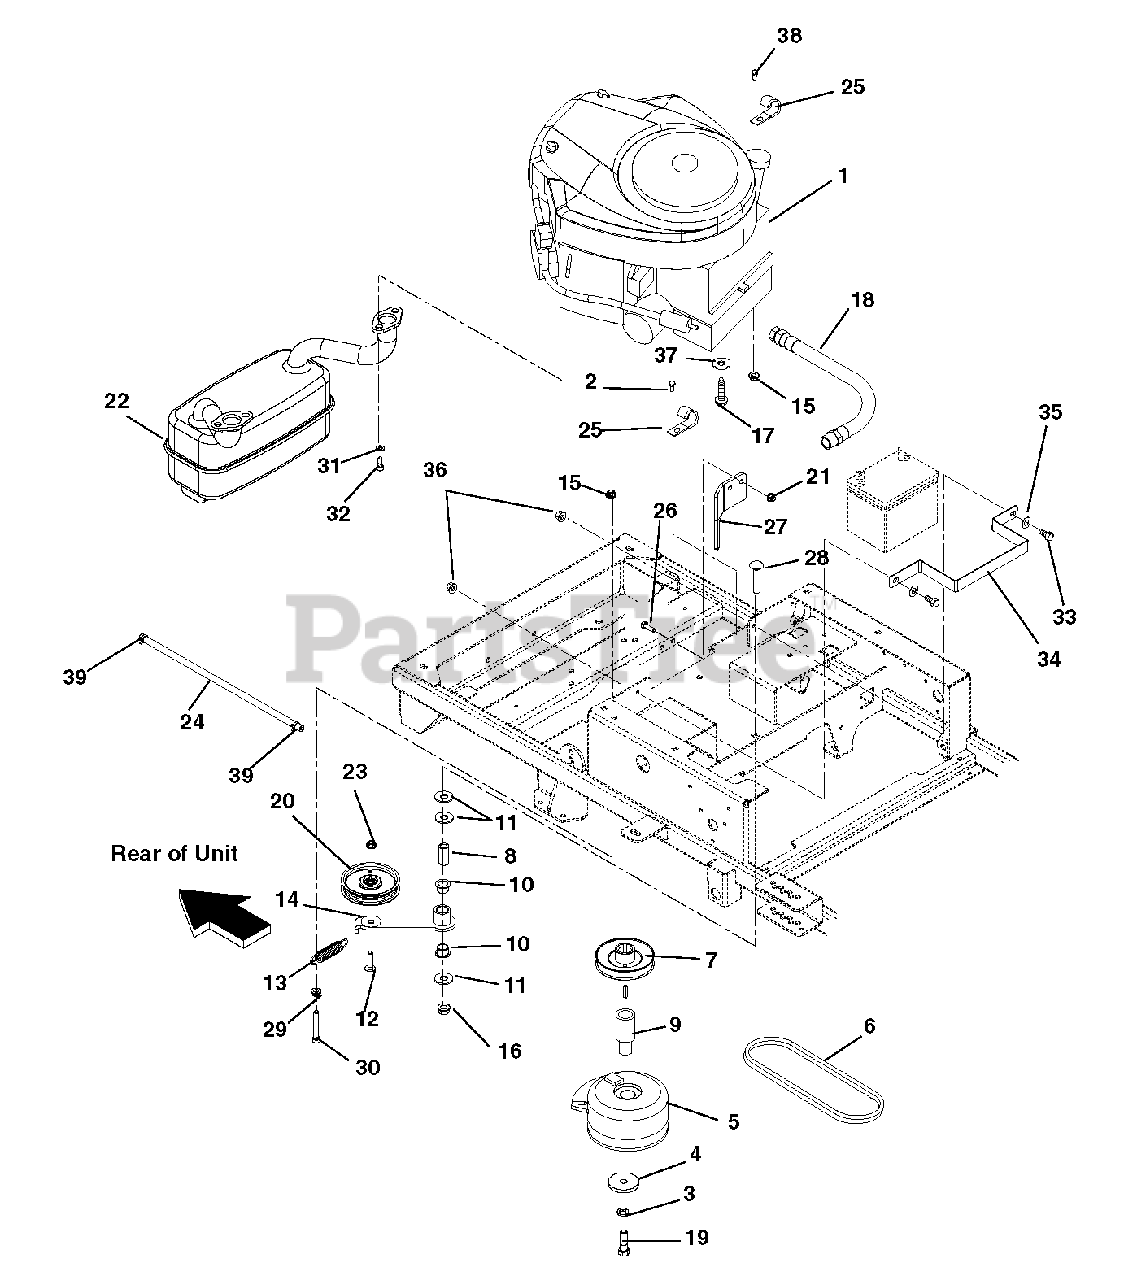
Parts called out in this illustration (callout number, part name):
1	Engine, FR651-22 Kawasaki Twin (915154)
2	Screw, Tapping .250-20 x .37 Hex Washer Head
3	Washer, Locking .44 x .109 Regular
4	Washer, Flat Steel .469 x 2.00 x .25
5	Clutch, ZTXL
6	Belt, HA 62.50 Wrapped
7	Pulley, V 4.5 x 1.5 AB Section with Key
8	Bushing, Sleave .500 x .750 x .1.560
9	External, Crankshaft Lower
10	Bushing, Flange 0.75 x 0.875 x .625 x 1.125
11	Washer, Flat Steel .563 x 1.38 x .109
12	Bolt, Round Head Square Neck .38-16 x 1.50 Grade 5
13	Spring, Tension .105 x .812 x 3.88
14	Weldment, Ground Drive Idler Arm
15	Nut, 3/8-16 Flange Nyloc
16	Nut, Locking Top Flange .50-13
17	Bolt, Hex .38-16 x 1.25
18	Hose Assembly, Oil Drain
19	Bolt, Hex .44-20 x 4.50 Grade 8
20	Assembly, 4" Idler
21	Nut, .31-18 Nyloc Flange
22	Muffler
23	Nut, Locking Top Flange .38-16
24	Assembly, Fuel Hose
26	Bolt, Hex .31-18 x 1.00 Grade 5
27	Clutch Stop
28	Bolt, Round Head Square Neck .50-13 x 2.50 Grade 5
29	Nut, Flange .375-16
30	Bolt, Hex .38-16 x 2.50 Grade 5
31	Washer, Locking .31 x .078 Regular
32	Screw, Cap .31-18 x .75
33	Bolt, Hex .25-20 x .75
34	Bracket, Battery Hold Down
35	Washer, Flat Steel .281 x .62 x .065
36	Nut, KEPS .250-20
37	Washer, Flat-Steel .406 x .812 x .065
38	Bolt, Hex .38-16 x .75 Grade 5
39	Clamp, Fuel Line
